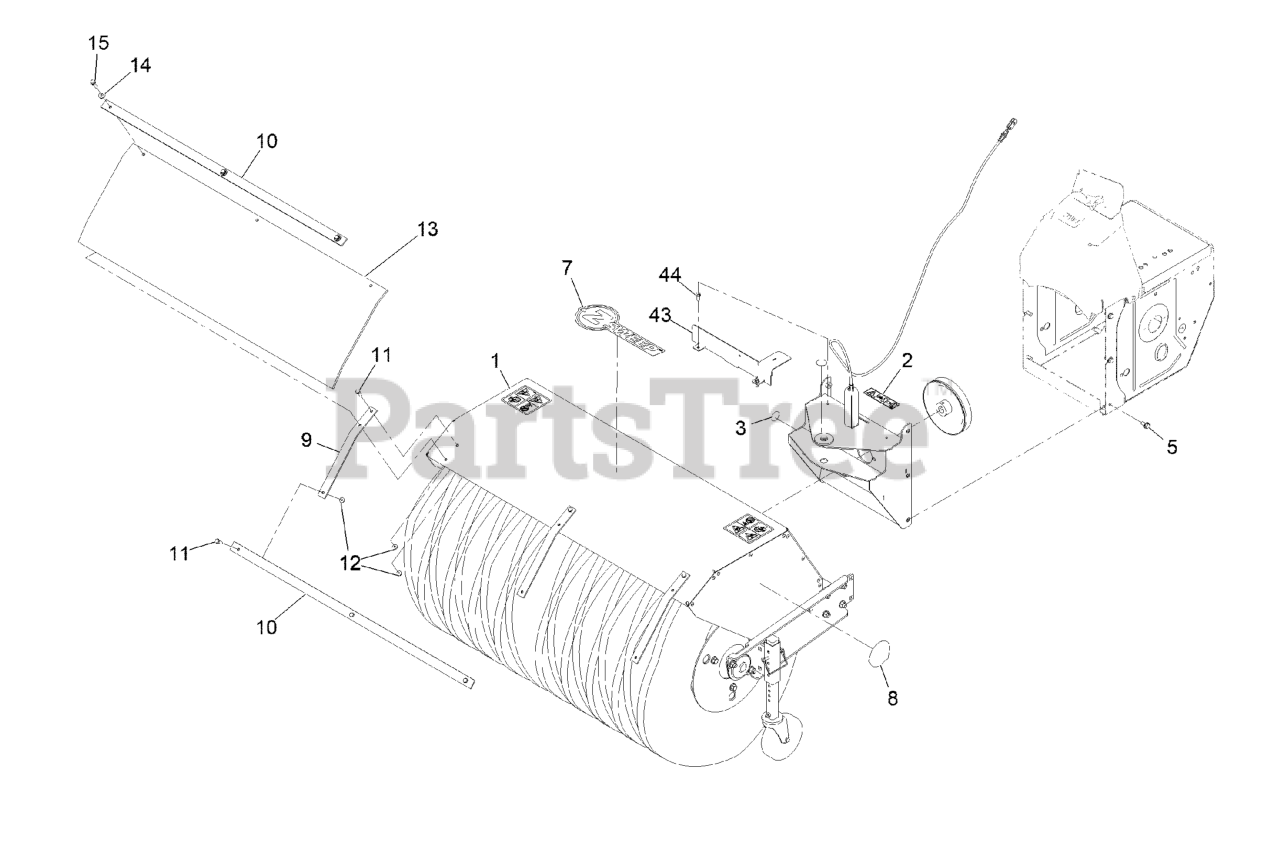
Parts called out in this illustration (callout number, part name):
1	Mb Broom
2	DECAL-COVER, MISSING
3	DECAL-GREASE
5	SCREW-HWHTF
7	DECAL-Z-SWEEP LOGO
8	Decal-Z-Logo
9	STRAP-SUPPORT, DEFLECTOR
10	STRAP-SUPPORT, BROOM DEFL
11	SCREW-HH
13	DEFLECTOR-BROOM
14	WASHER-FLAT
15	SCREW-HHF
43	PLATE-COVER
44	SCREW-HWH
